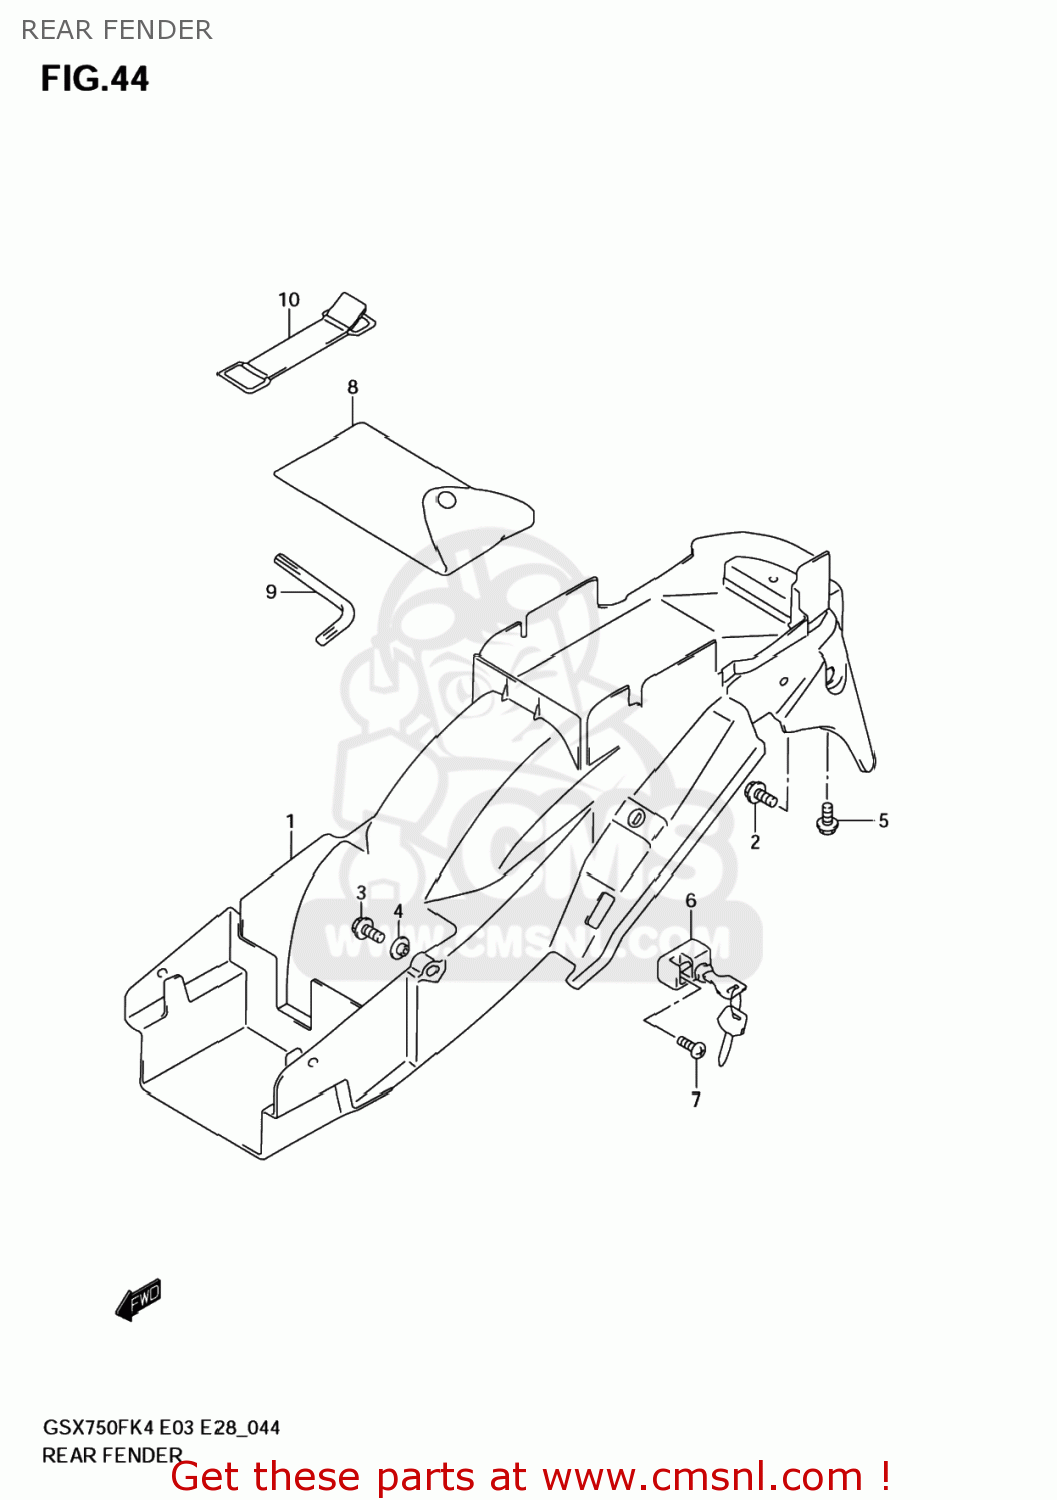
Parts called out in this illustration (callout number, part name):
1	FENDER,RR
2	BOLT(6X16)
3	BOLT
4	WASHER
5	BOLT(6X16)
6	LOCK SET,HELMET
7	SCREW(6X14)
8	TOOL ASSY
9	SPANNER,HEXAGON
10	BAND,TOOL
